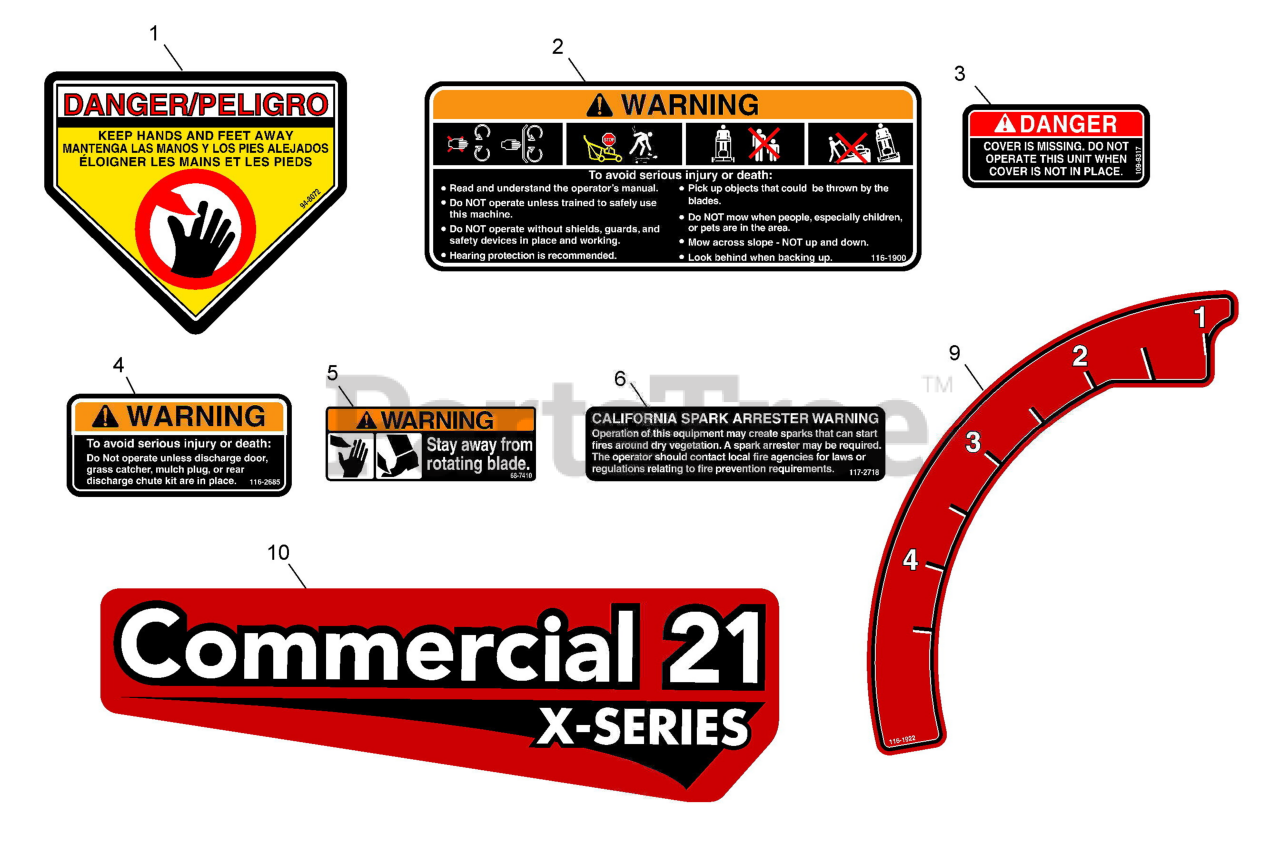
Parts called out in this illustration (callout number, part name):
1	DECAL-DANGER
2	DECAL-WARNING
3	DECAL-COVER MISSING
4	DECAL-WARNING DOOR SM
5	DECAL-BLADE
6	DECAL-ARRESTER, SPARK
9	DECAL-HEIGHT OF CUT
10	DECAL-COMM 21 X-SERIES
